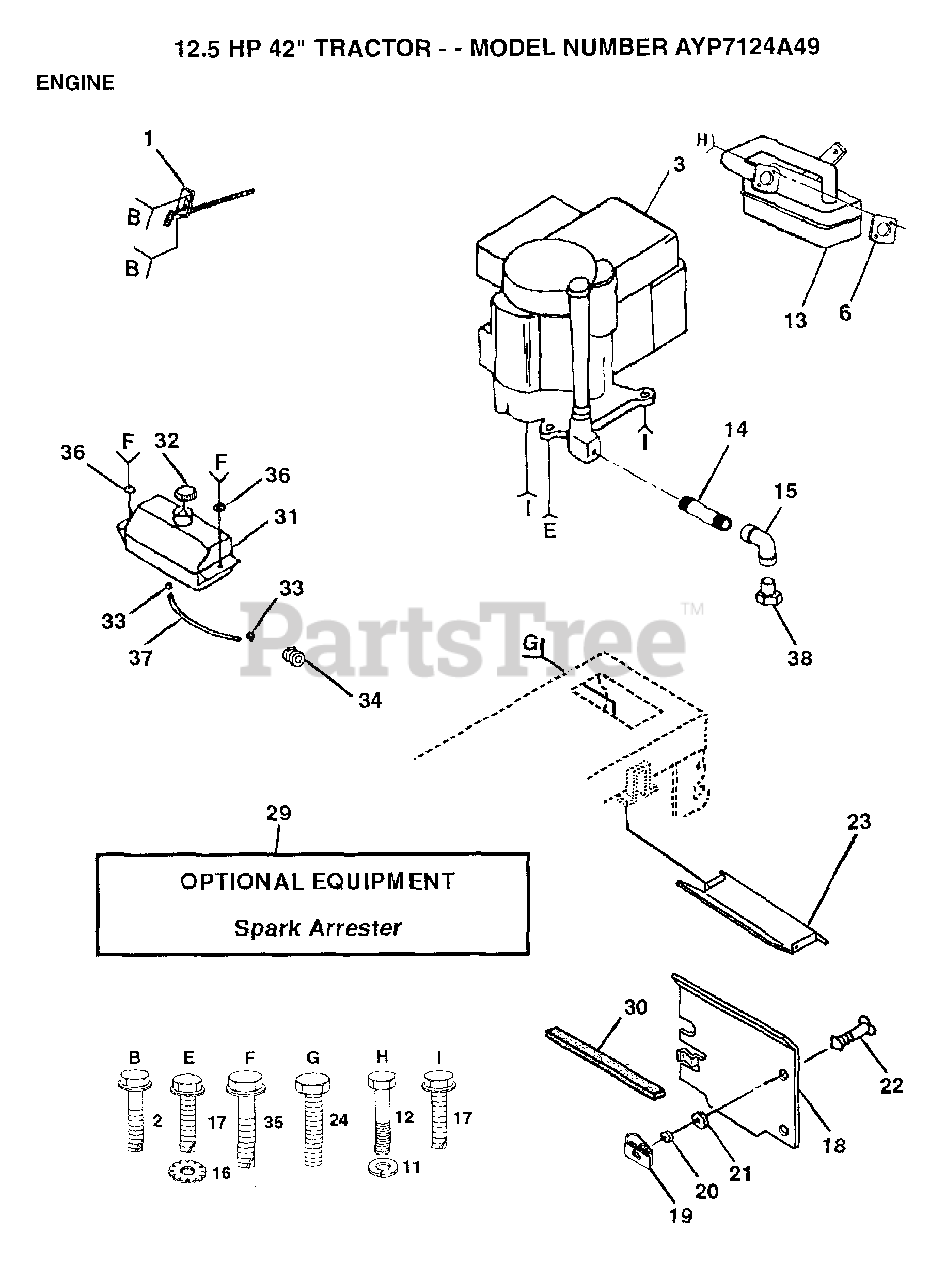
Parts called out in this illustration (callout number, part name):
2	SCREW LT
11	LOCKWASHER
12	SCREW
13	MUFFLER
14	PIPE NIPPLE
15	ELBOW
16	LOCKWASHER
17	SCREW
18	SHIELD HEAT
19	RECEPTACLE LT
20	RETAINER LT
21	WASHER
22	STUD.1/4.TURN
31	TANK.FUEL.LT.
33	HOSE CLAMP
35	SCREW HEX CRT
36	WASHER
37	FUEL LINE T
